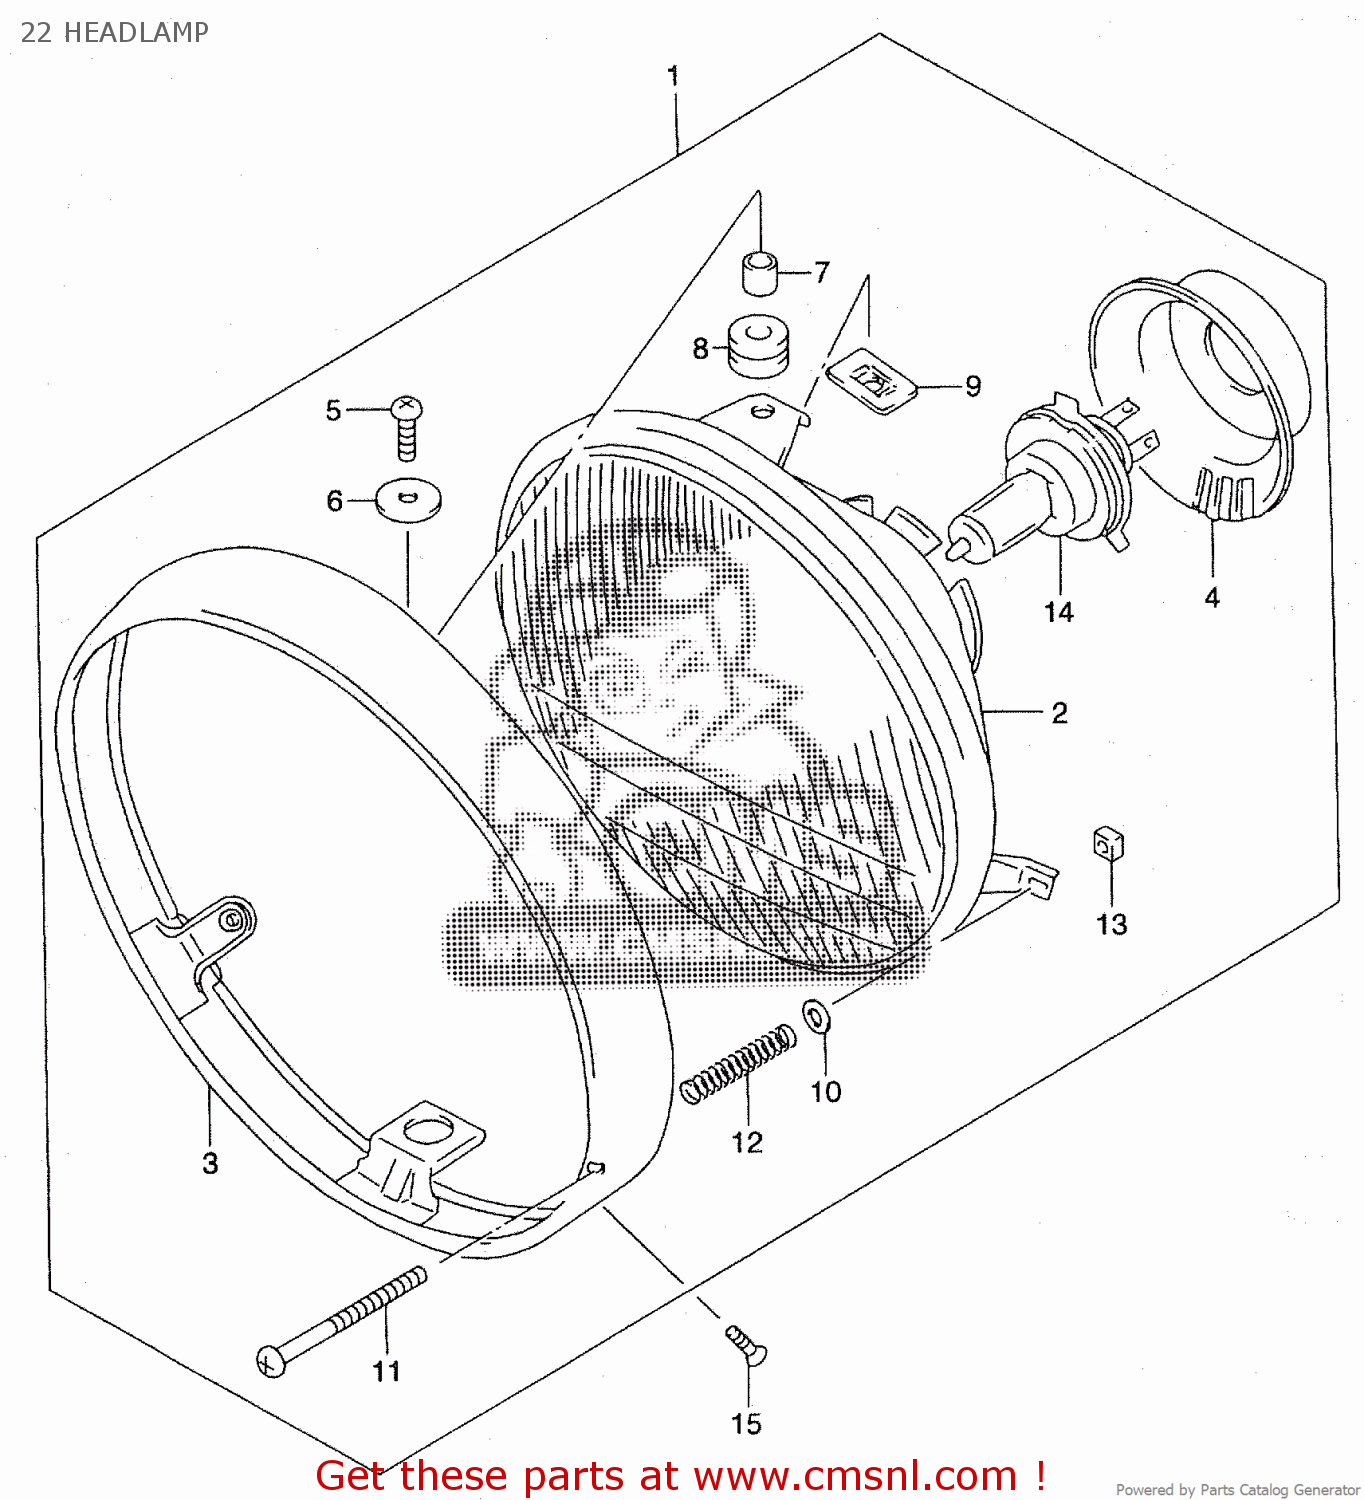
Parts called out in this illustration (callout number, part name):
1	HEADLAMP ASSY
2	LAMP UNIT
3	RIM,HEAD LAMP
4	COVER,SOCKET
5	SCREW(5X14)
6	WASHER(5.5X18X1)
7	SPACER
8	CUSHION
9	NUT
10	WASHER
11	SCREW(4X50)
12	SPRING,HEADLAMP ADJUST
13	NUT
14	BULB(12V60/55W ,YELLOW)
15	SCREW(5X12)
